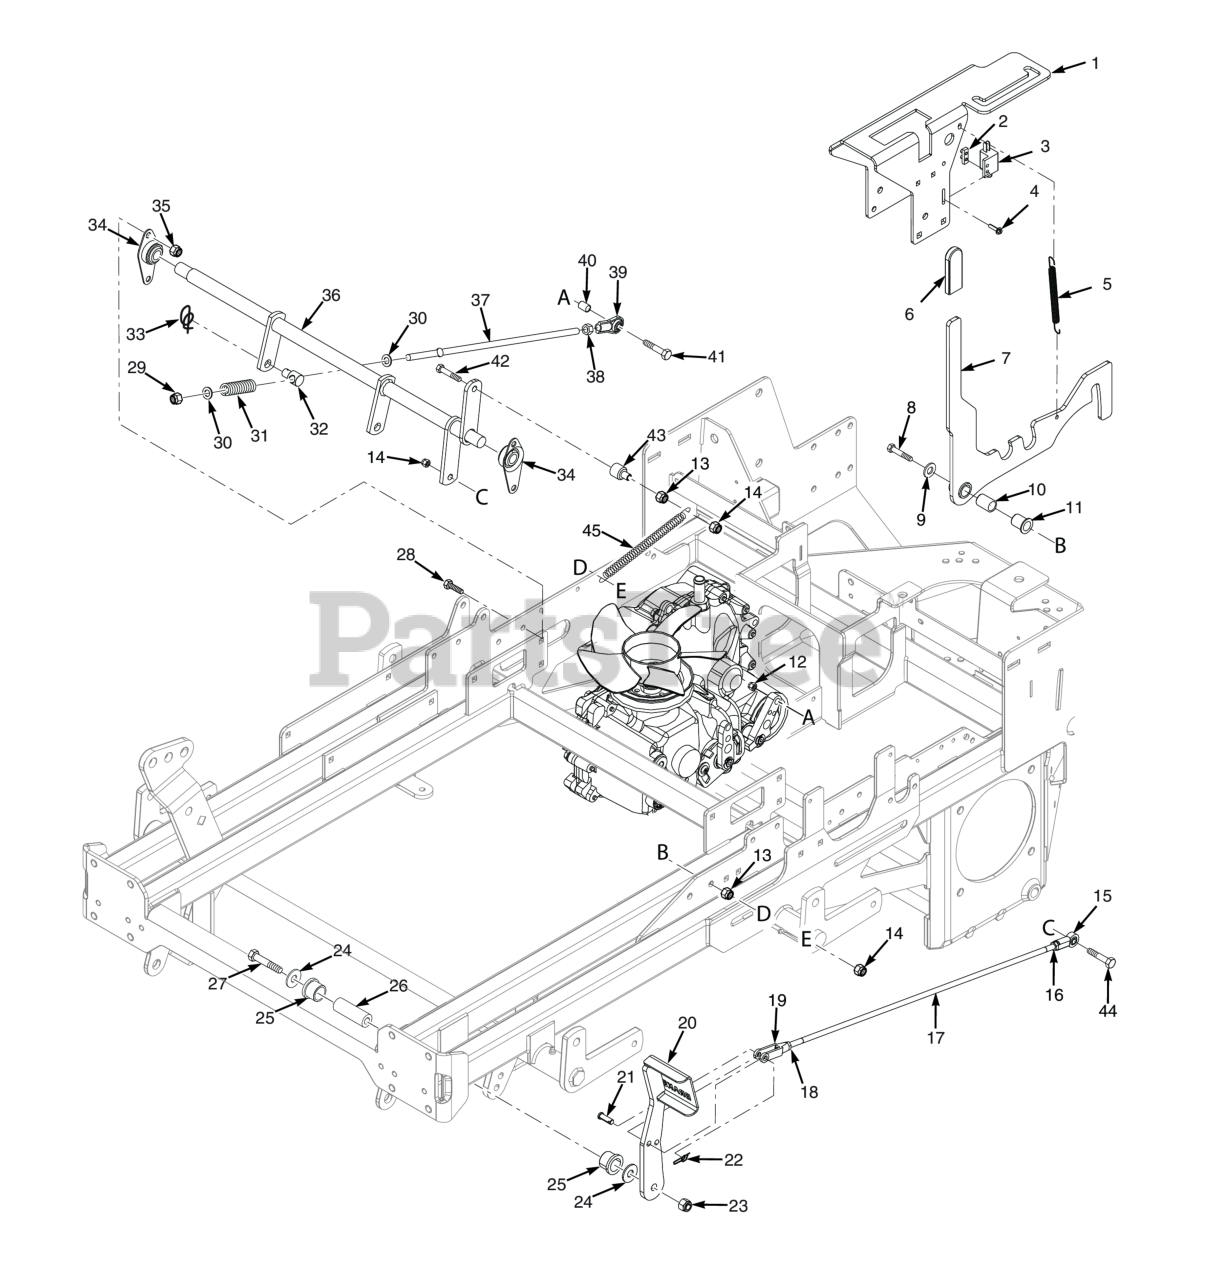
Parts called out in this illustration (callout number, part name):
1	Control Weldment w/ Decal
2	Plate, Threaded
3	Switch, N/C
4	Screw, Hex-Slotted Washer Head #10 32 x 3/4"
5	Spring, Deck Latch
6	Grip, Brake Handle
7	Brake Lever w/ Grip
8	Capscrew, Hex Head 3/8-16 x 2-1/2"
9	Flatwasher, 3/8 (.391 x .938 x .105 HD) Grade 8
10	Pivot, Brake Lever
11	Bearing, .625 ID Plastic
12	Nut, Center Lock, 5/16-18(32)
13	Bolt, Hex Head 3/8-16 x 1" Ser. Flg.
14	HEX NUT, ELASTIC STOP LOCK, 3/8-16
15	Rod End, 3/8-24 LH Thread Female
16	Nut, 3/8-24 UNF-2B LH Thread
17	Brake Rod Assembly (INCL. 15,16,18,19)
18	Nut, 3/8-24 UNF R.H. Thread
19	Clevis, Traction Control
20	Brake Pedal
21	Pin, Clevis 3/8-16 x 1-1/16"
22	Pin, Rue Cotter 3/8" Diameter
23	HEX LOCKNUT, ELASTIC STOP, 1/2-13
24	Flat Washer, 1/2 (.562 x 1.375 x .109)
25	Bearing, Plastic
26	Sleeve, Brake Pivot
27	Bolt, Hex Head 1/2-13 x 4-1/4"
28	BOLT, SERRATED FLANGE HEX HEAD 5/16-18 X 3/4"
29	Nut, Elastic Stop 3/8-24
30	FW, .375-.376/.380 X .734 X .063
31	Spring
32	BUSHING, PIVOT SLIDE
33	Pin, Rue Cotter 1/2" Dia.
34	Bearing, Self Align
35	Nut, Flange Head Elastic Stop 5/16-18
36	Brake Linkage Weldment
37	Brake Linkage Assembly (INCL. 29,30,31,32,38,39)
38	HEX NUT, 3/8-24 R.H. THREAD
39	Rod End, 3/8-24
40	Spacer, Pump
41	Bolt, 5/16-18 x 2-1/2"
42	Capscrew, Hex Head 3/8-16 x 2.75"
43	Pivot, Idler - Short
44	BOLT, HEX HEAD, 3/8-16 X 1-1/4
45	SPRING, HOPPER DOOR
